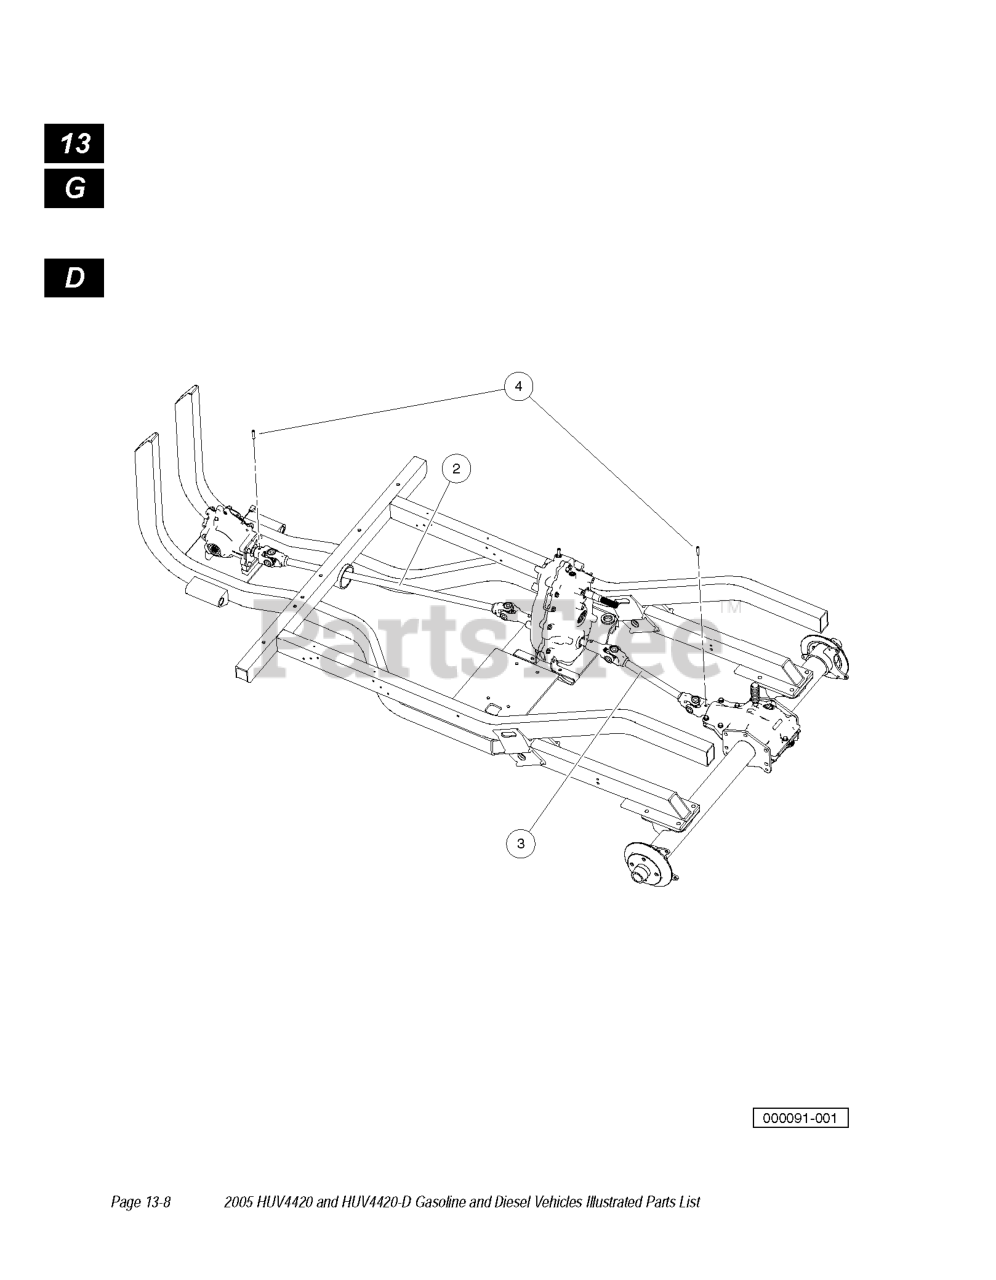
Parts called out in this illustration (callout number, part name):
2	PROP SHAFT, FRONT
3	PROP SHAFT, REAR - 105173301
4	PIN, SPRING, 5/16 X 1-1/2 HD
